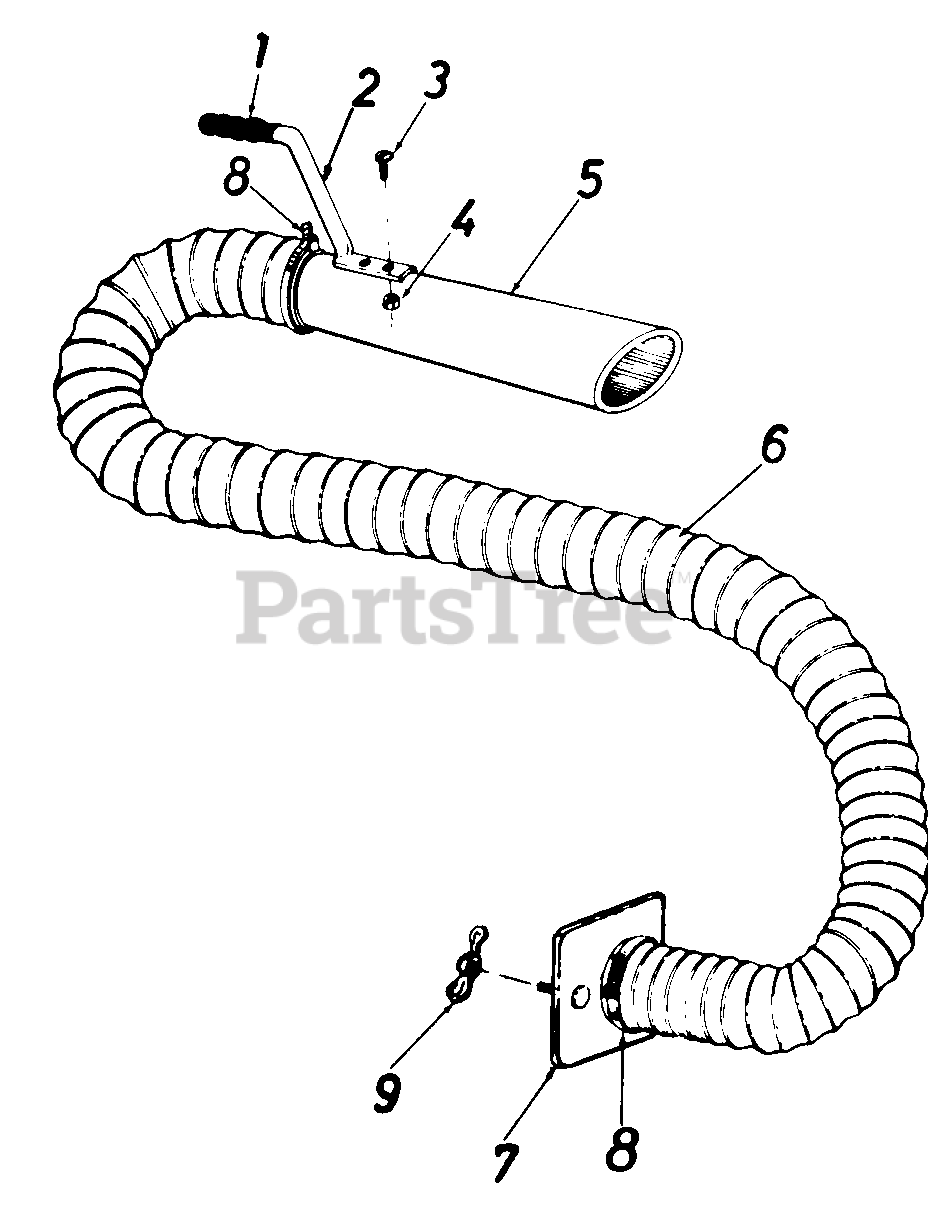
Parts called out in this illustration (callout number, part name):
1	GRIP-BLACK
2	HANDLE-HOSE NOZ LONG
3	SCREW-TRUSS SEMS #10-24 X .50
5	NOZZLE-HOSE
6	HOSE-4IN DIA X 10FT
7	PLATE ASSY-HOSE ADAPTER
8	CLAMP-HOSE
9	NUT-WING-SOLID 1/4-20
